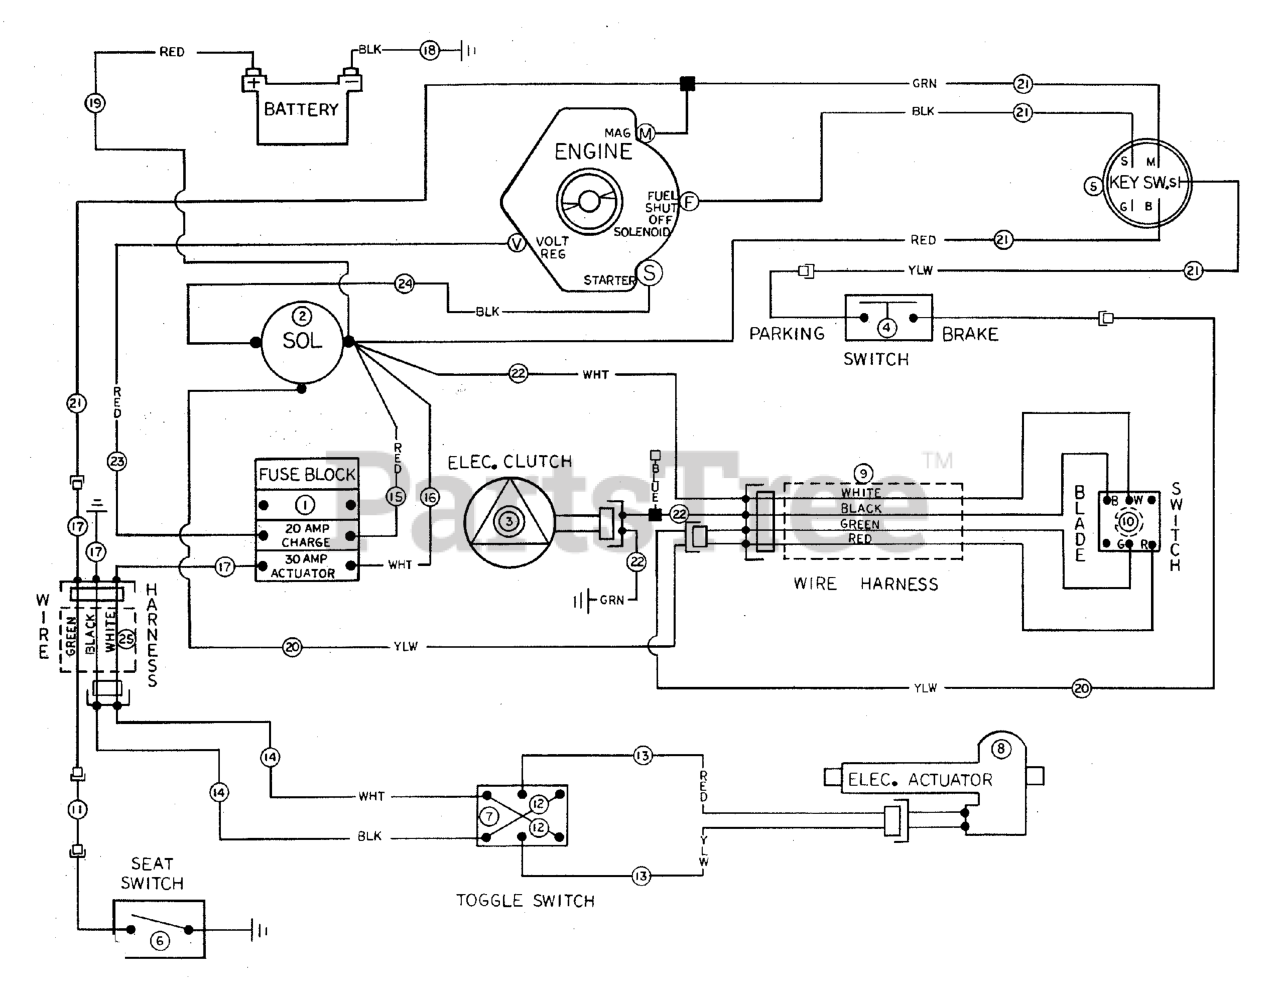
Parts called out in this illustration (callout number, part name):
1	Fuse Block
1	20 Amp Fuse
1	30 Amp Fuse
2	SOLENOID, Starter
3	CLUTCH, Electric, 1" Shaft
4	Parking Brake Switch Assembly
5	SWITCH, IGNITION, 6 POST
6	Seat Switch Assembly
7	Toggle Switch
8	Electric Actuator
9	Elecric Clutch Alpha Cable Assembly
10	Toggle Switch
11	Green Alpha Cable to Seat Switch
12	Red Corner to Corner Toggle Switch
13	Toggle Switch to Actuator Harness
14	Actuator Switch to Alpha Cable Harness
15	Red Fuse Block to Solenoid
16	White Fuse Block to Solenoid
17	Actuator to Control Panel Harness
18	Negative Battery Cable
19	Positive Battery Cable
20	Switch to Solenoid Cable Assembly
21	Key Switch Harness
22	Electric Clutch Harness
23	Engine Charging to Fuse Block
24	Solenoid to Starter
25	Electric Actuator Alpha Cable Assembly
